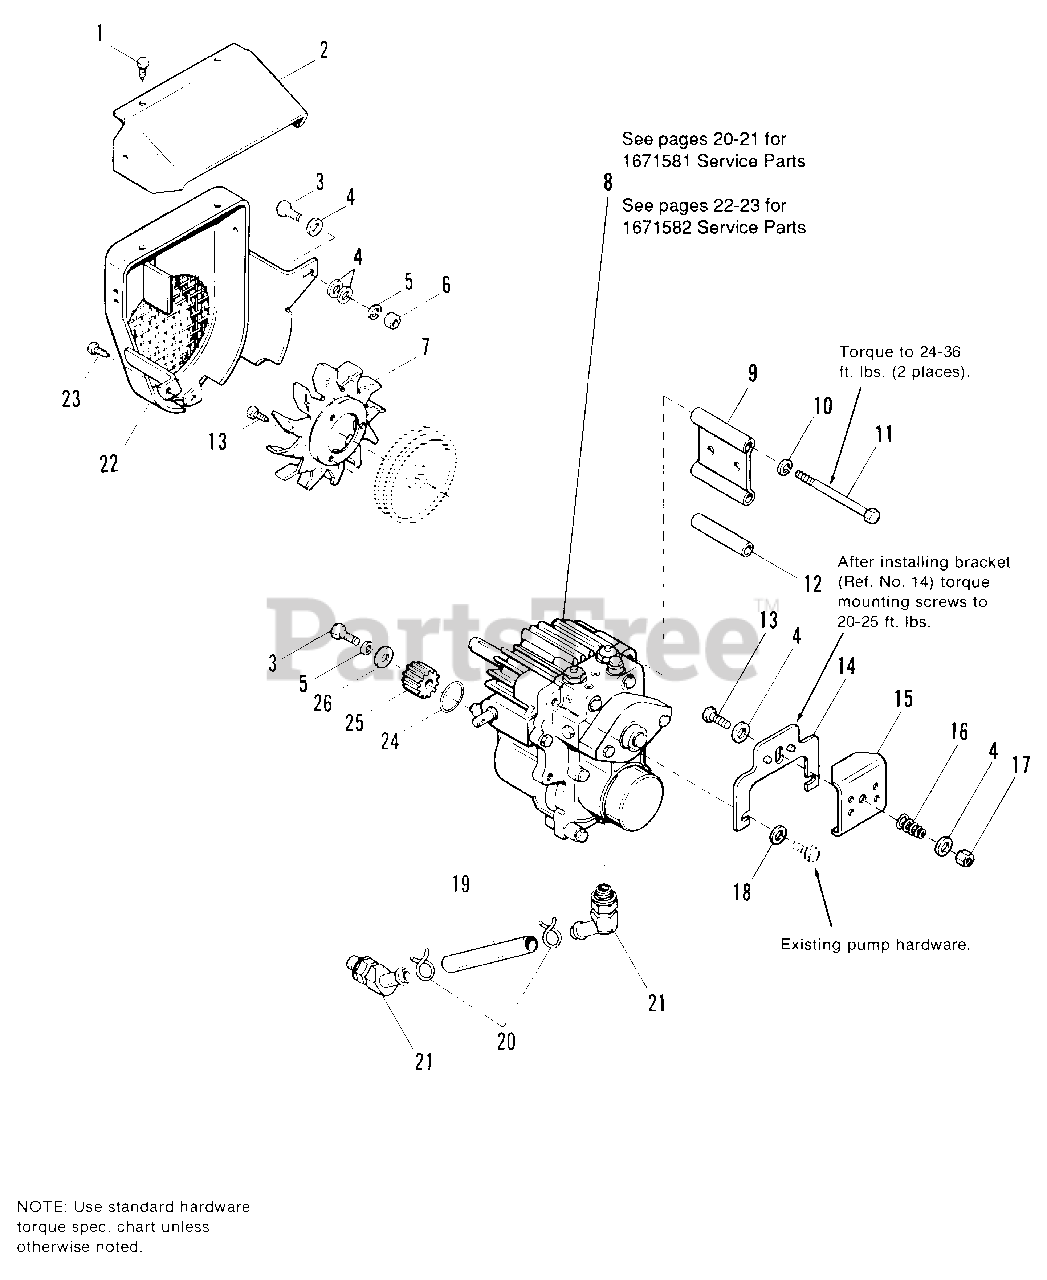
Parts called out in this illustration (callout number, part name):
1	SCREW, Self-Tapping, #10-3/8
2	DEFLECTOR, Shroud
3	CAPSCREW, Hex Hd., 5/16-18 x 1
4	WASHER, Plain, 5/16
5	LOCKWASHER, 5/16
6	NUT, Hex, Full, 5/16-18
7	FAN, Pulley
8	HYDRO PUMP, (for Manual Lift Models, see pages 20-21 for Service Parts)
8	HYDRO PUMP, (for Hydro Lift Models, see pages 22-23 for Service Parts)
10	LOCKWASHER, 3/8
11	CAPSCREW, Hex Hd., 3/8-16 x 5
12	SPACER
13	SCREW, Hex, Washer Hd., Taptite, 1/4-20 x 3/8
15	LATCH, Release
17	LOCKNUT, Hex, 5/16-18
19	HOSE, Inlet
20	CLAMP, Hose
21	ELBOW, Hose Fitting
22	SHROUD ASSY., w/Screen
23	SCREW, Hex, Washer Hd., Taptite, 5/16-18 x 3/4
25	PINION, Motor Shaft
